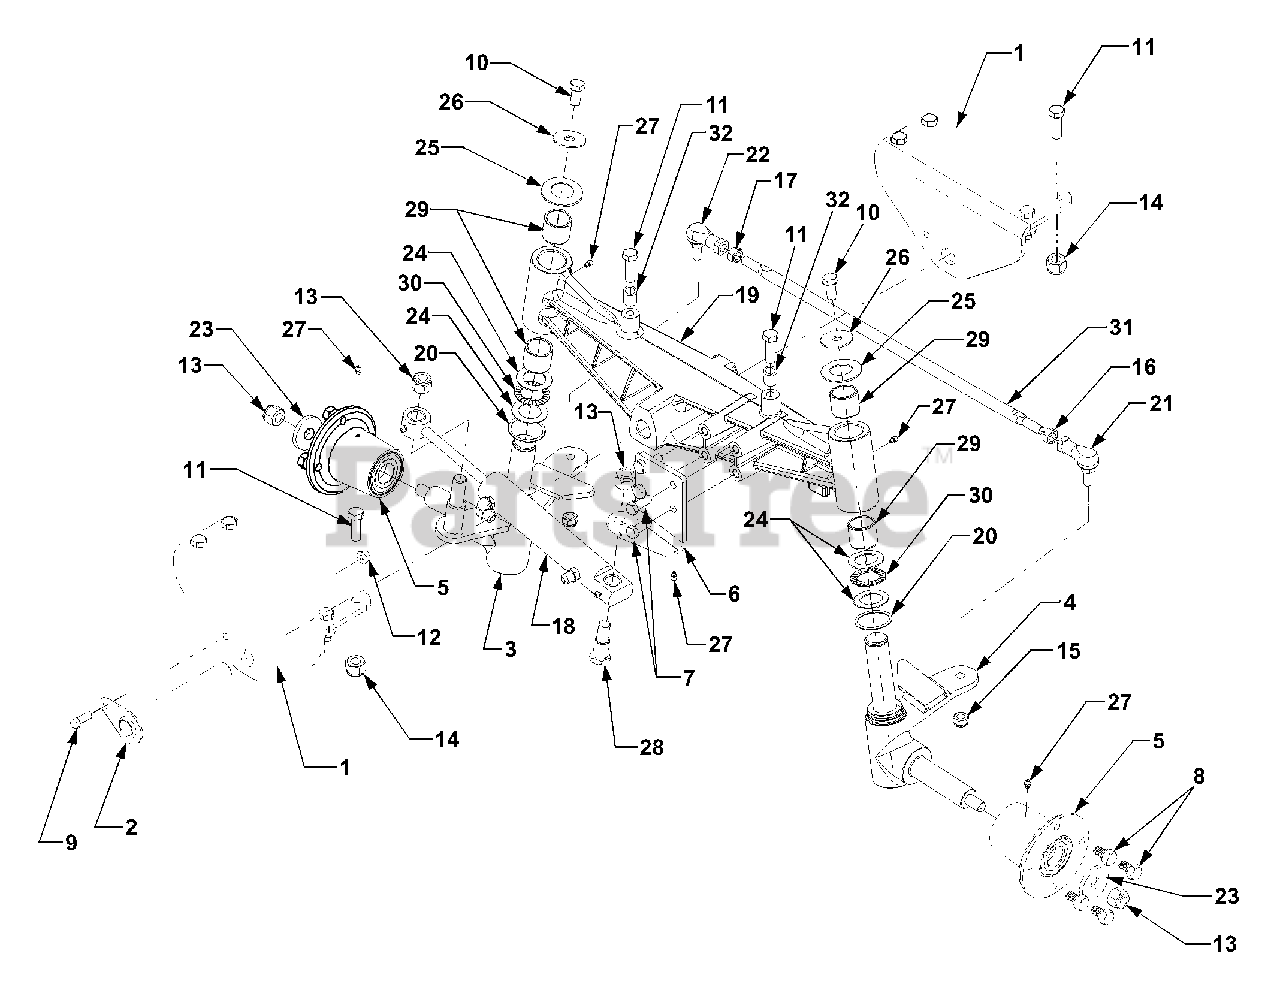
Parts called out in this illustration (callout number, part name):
1	Bracket, Axle Mounting
2	Pin, Pivot Axle
3	Spindle Assembly, Steering LH
4	Spindle Assembly, Steering RH
5	Hub Assembly
8	Bolt, Lug, M12-1.75 x 14 GR8.8
9	Screw, Hex Cap Lock 3/8-16 x 1.0 GR5
10	Screw, Hex Cap Lock 1/2-13 x 1.0 GR5
11	Screw, Hex Cap 1/2-13 x 1.5 GR5
12	Nut, Hex Flange Lock, 3/8-16 GR5
13	Nut, Hex Insert Lock 5/8-11 GR5
14	Nut, Hex Insert Lock, 1/2-13 GR8
15	Nut, Hex Flange Lock, M12 x1.75
16	Nut, Hex, M12 x 1.75 RH Thrd
17	Nut, Hex, M12 x 1.75 LH Thrd
18	Cylinder, Steering
19	Axle, Pivot
20	O-Ring, 1.374 x .139
21	Ball Joint, RH Thrd
22	Ball Joint, LH Thrd
23	Washer, Flat, .66 x 1.94 x .25
24	Washer, Flat, 1.25 x 1.94 x .063
25	Washer, Flat, 1.25 x 2.25 x .040
26	Washer, Flat, .531 x 1.75 x .09
27	Fitting, Lube, 3/6 Drive
28	Screw, Shoulder, .75 x 1.03
29	Bearing, Sleeve, 1.25x1.5x1.25
30	Bearing, Thrust, 1.25 x 1.94 x .78
32	Spacer, .501 x .75 x .78
